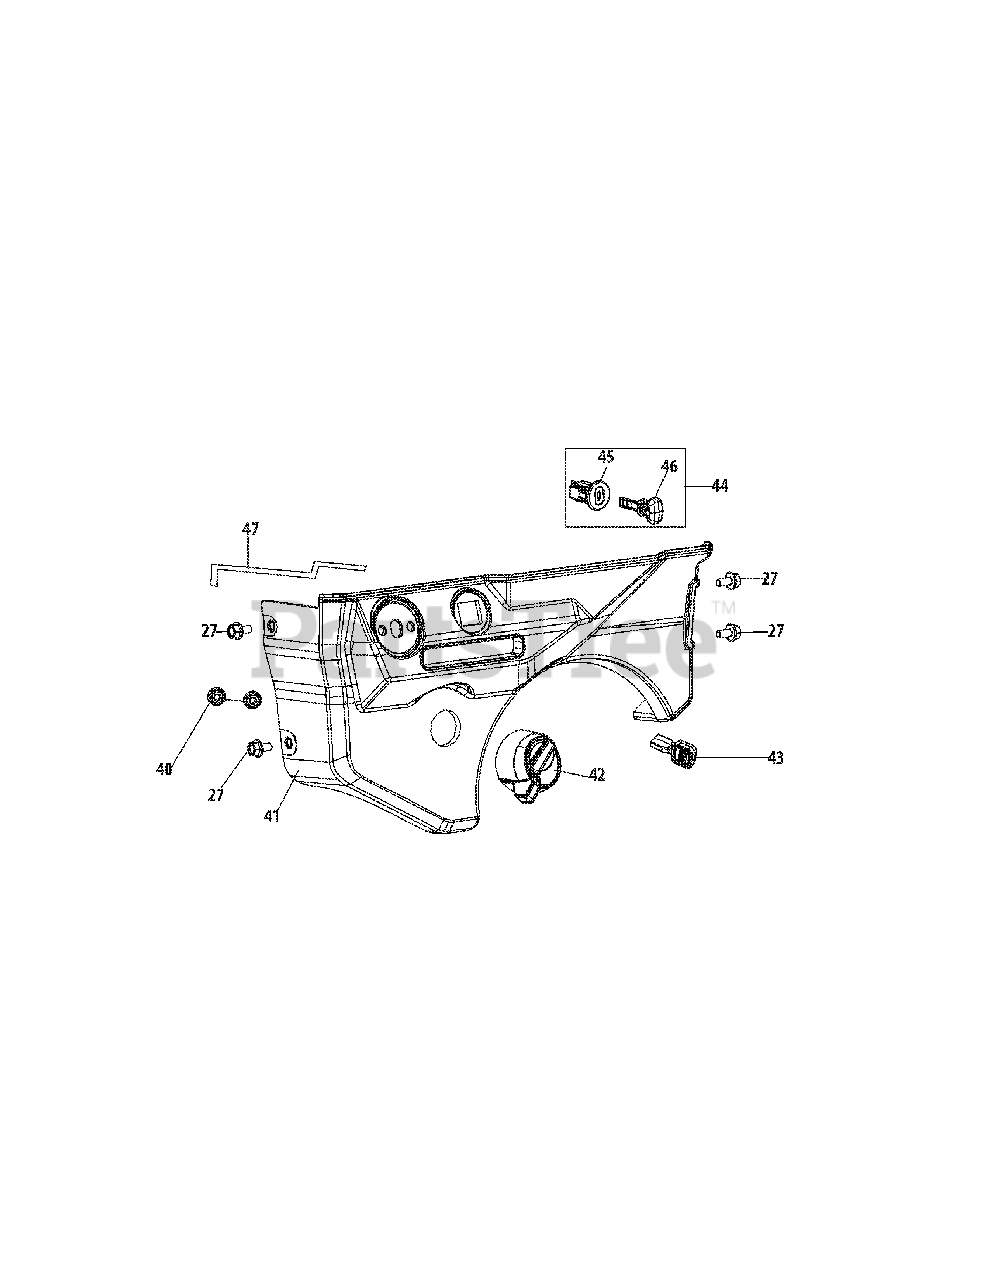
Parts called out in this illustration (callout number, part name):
27	Bolt, M6×12
40	Nut, M6
41	Control Panel
42	Choke Lever
43	Throttle Lever Knob
44	Stop Switch
45	Stop Switch Base
46	Stop Switch Key
47	Choke Linkage
